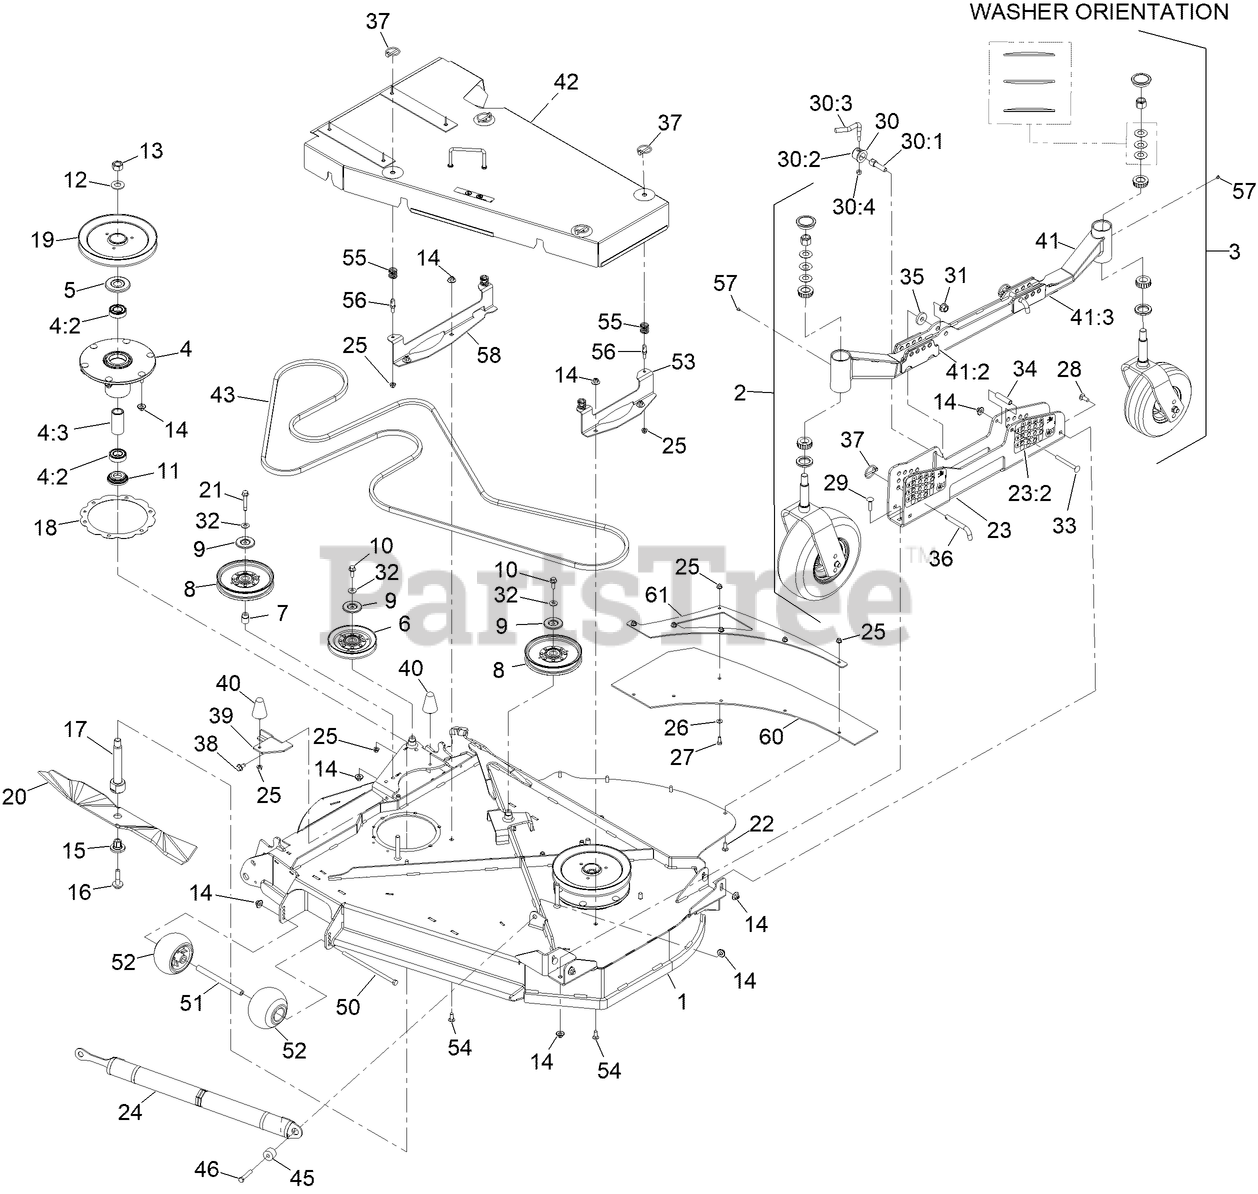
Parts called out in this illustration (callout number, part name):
1	ASM-LH WING DECK 144
2	CASTER WHEEL ASM
3	REAR CASTER WHEEL ASM
4	SPINDLE ASM
4:2	BEARING-BALL
4:3	SPACER-BEARING
5	GUARD-BEARING, TOP
6	IDLER-V
7	BUSHING-IDLER
8	IDLER-PULLEY
9	SHIELD-DUST
10	SCREW-HHF
11	GUARD-BOTTOM
12	WASHER
13	NUT-HEX
14	NUT-FLANGE, NI
15	BUSHING-HEX
16	SCREW-SEMS
17	SHAFT-SPINDLE
18	RING-SPACER, HOUSING
19	SHEAVE-DRIVE, BLADE
20	BLADE-24.50 MULCH
21	SCREW-HHF W/ PATCH
22	BOLT-CARR
23	ASM-CHANNEL, HOC LH
23:2	DECAL-HEIGHT OF CUT-LH
24	ASM-WEIGHT-TRANSFER-SPRING
25	NUT-HF, NI
26	WASHER-PLAIN
27	SCREW-HH
28	BOLT-CARR
29	SCREW-CARR
30	LEVER ASM
30:1	SCREW-LOCK
30:2	CAP-LOCK
30:4	NUT-LOCK, NI
31	NUT-LOCK
32	WASHER-BELLEVILLE
33	SCREW-CARR
34	SPACER
35	WASHER
36	PIN-HOC
37	PIN-LYNCH
38	SCREW-HWH
39	BRACKET-COVER RETAINER
40	BUMPER-RUBBER
41	ASM-LH GAUGE WHEEL ARM
41:2	PLATE-GUIDE, FRONT
41:3	PLATE-GUIDE, REAR
42	ASM-BELT SHIELD
45	BUSHING-LIFT SPRING
46	SCREW-HH
50	SCREW-HH
51	SPACER-WHEEL
52	ROLLER-SCALP, ANTI
53	BRACKET-SHIELD MOUNT, OUTER
54	BOLT-CARR
55	SPRING
56	PIN, SPRING
58	BRACKET-SHIELD MOUNT, OUTER LONG
60	GUARD-LH REAR WING
61	SUPPORT-LH REAR GUARD
